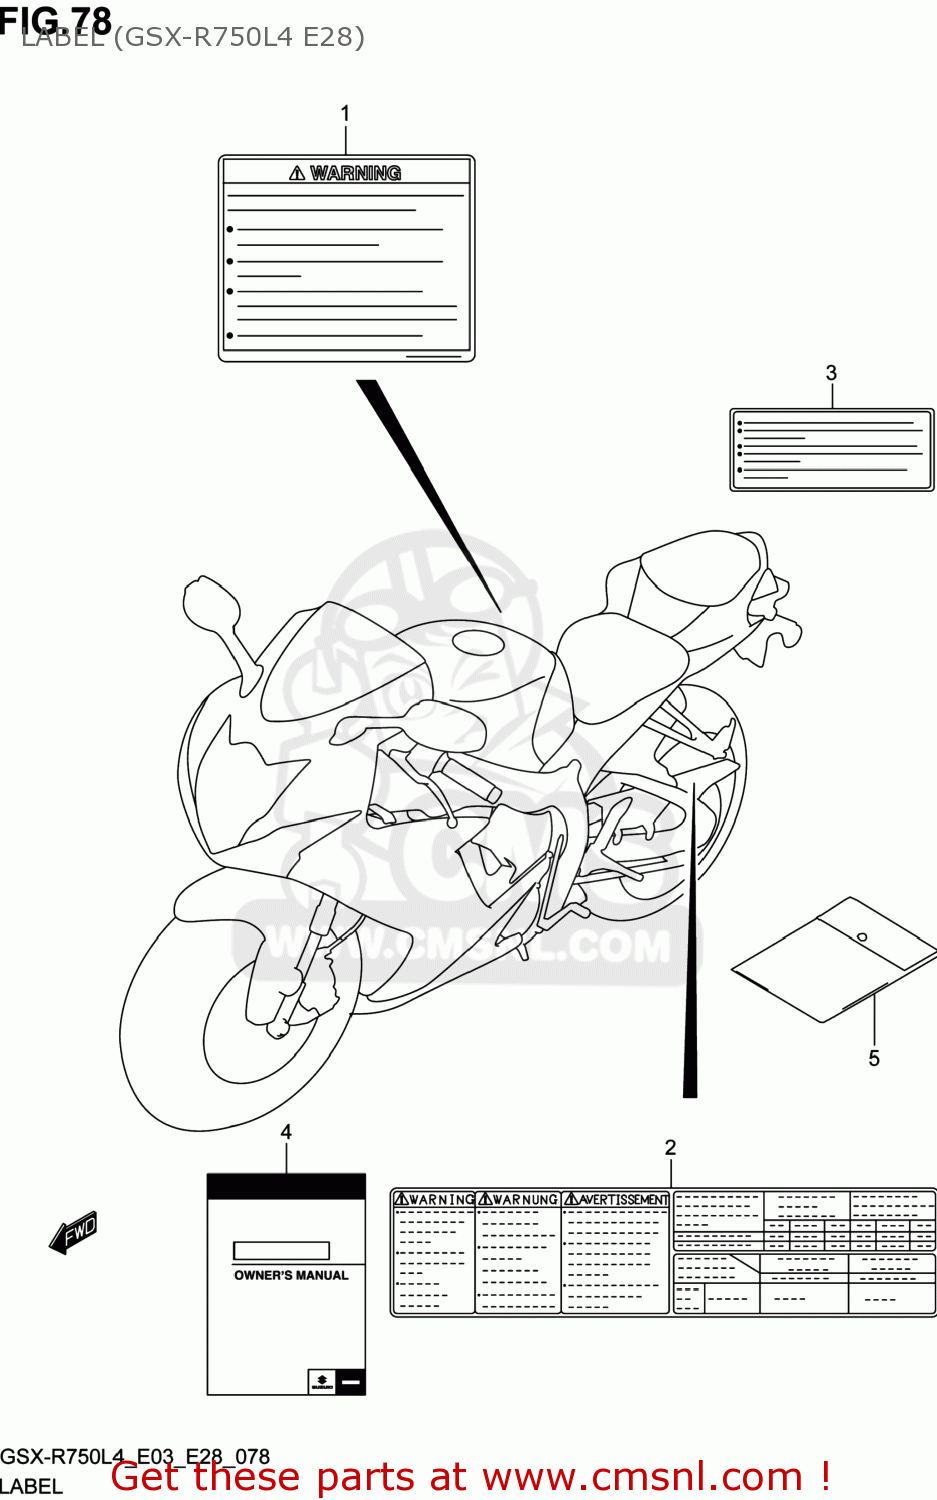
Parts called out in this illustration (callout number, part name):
1	LABEL,GENERAL WARNING
2	LABEL,TIRE INFORMATION
3	LABEL,FUEL INFORMATION
4	MANUAL,OWNER'S
5	BAG,OWNER'S MANUAL
